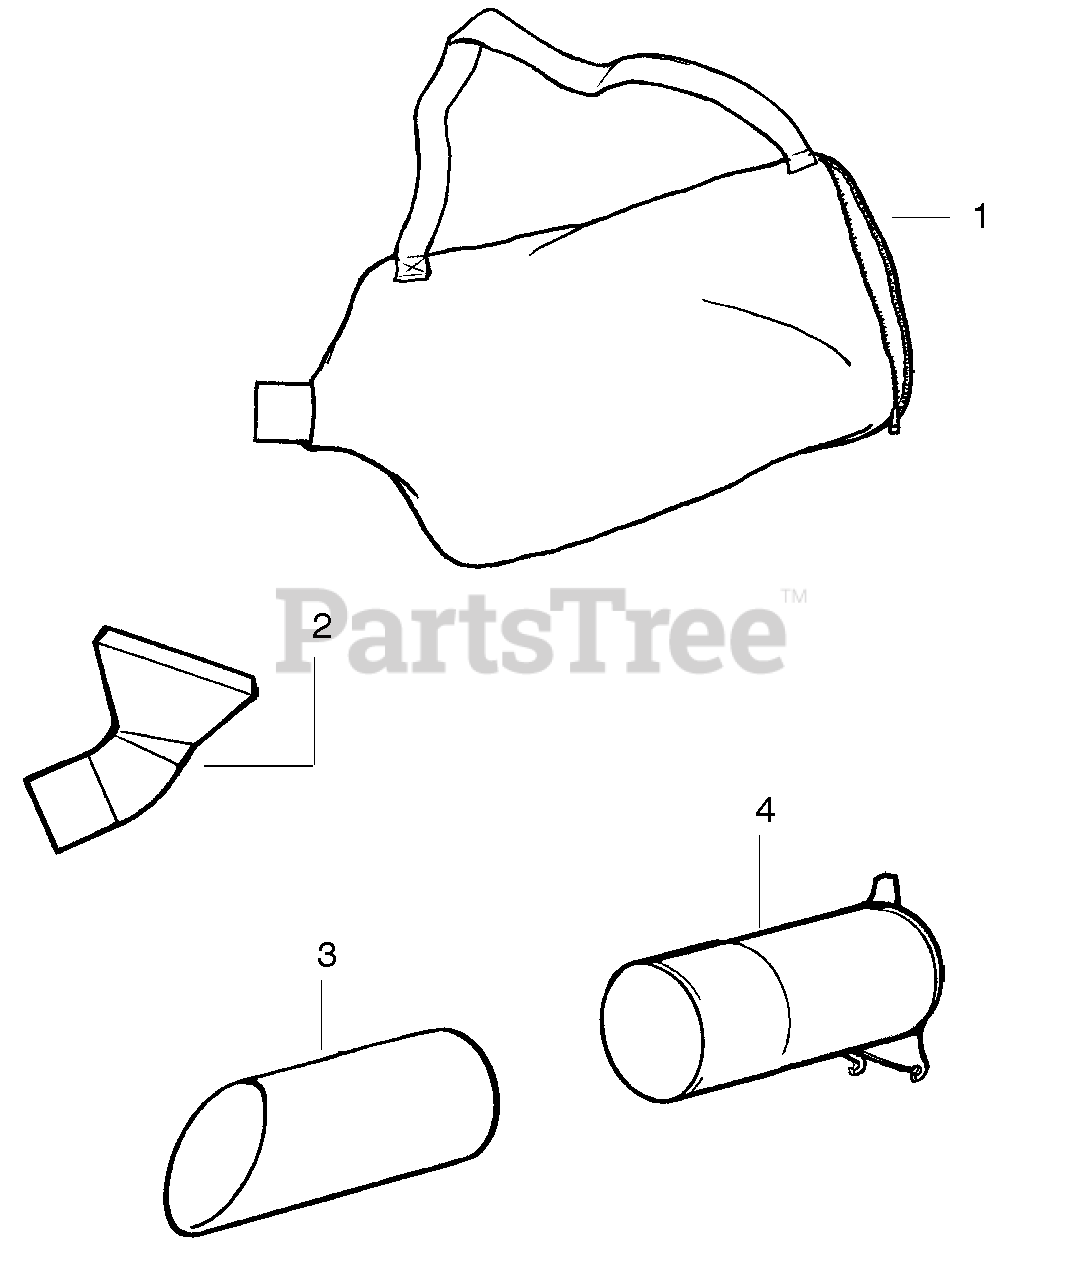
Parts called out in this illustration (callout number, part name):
1	Assy-Vac. Bag w/strap
2	Tube-Elbow Vac
3	Tube-Lower Vac
4	Tube-Upper Vac
